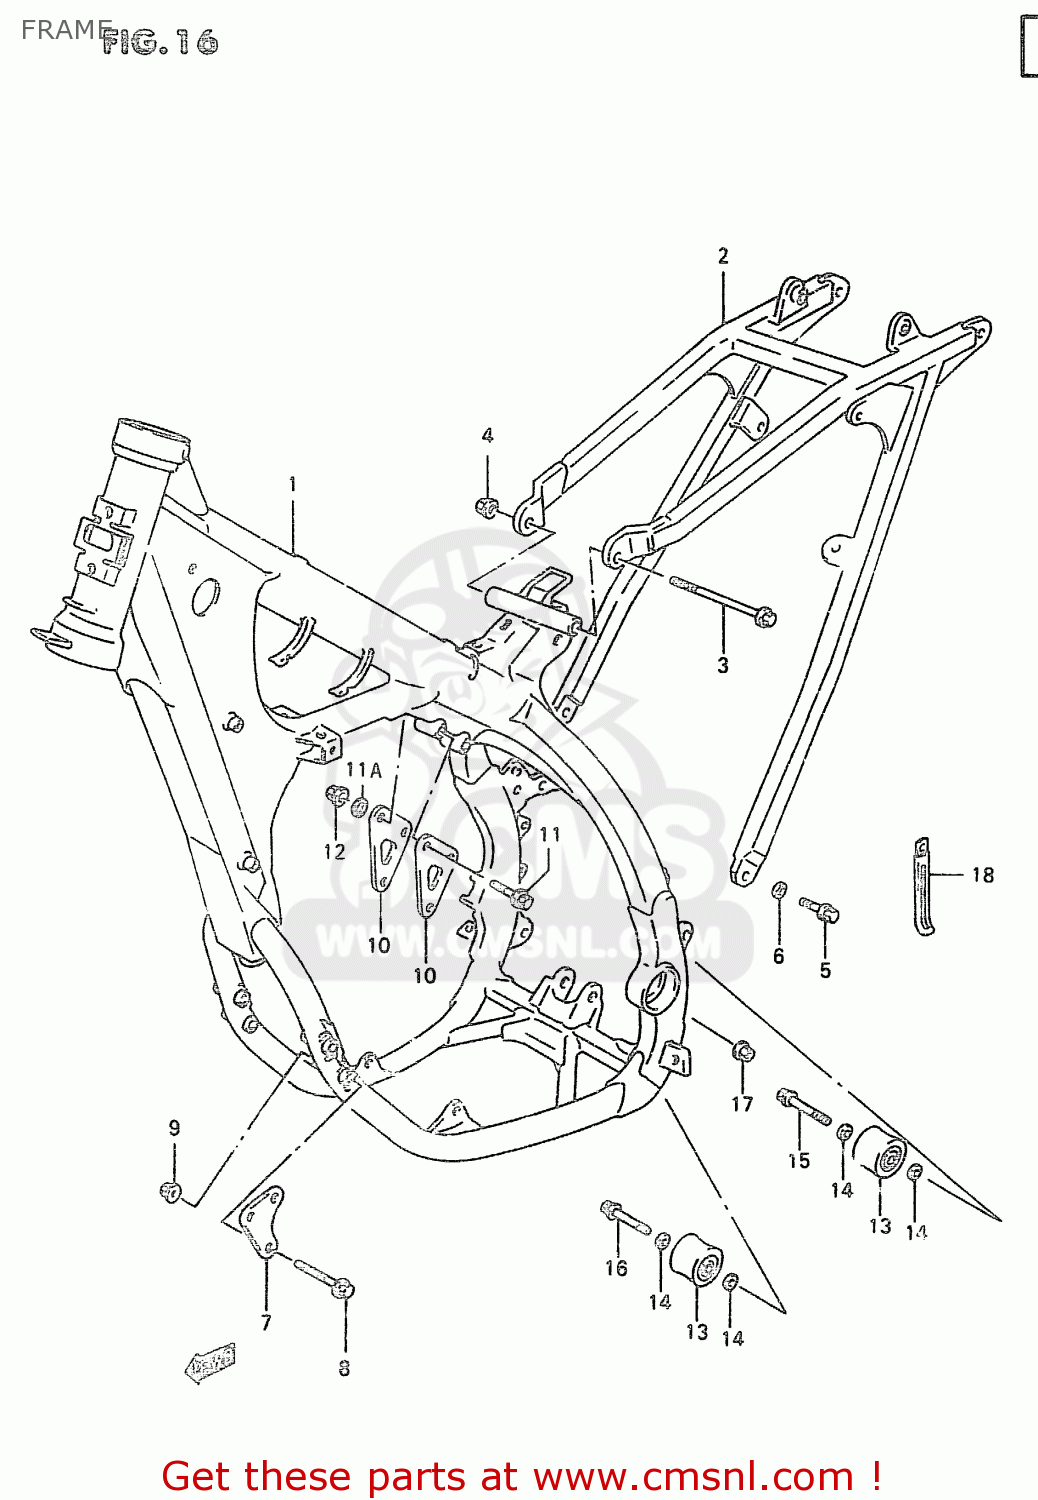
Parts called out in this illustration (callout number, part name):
1	FRAME COMP
2	RAIL,SEAT
3	BOLT(8X120)
4	NUT
5	BOLT 8X16
6	WASHER
7	PLATE,ENGINE MOUNTING
8	BOLT
9	NUT
10	PLATE,ENG MTG UPR
11	BOLT(8X45)
11A	WASHER
12	NUT
13	ROLLER,CHAIN
14	WASHER
15	BOLT(8X41)
16	BOLT(8X45)
17	NUT
18	CLAMP(L:65)
